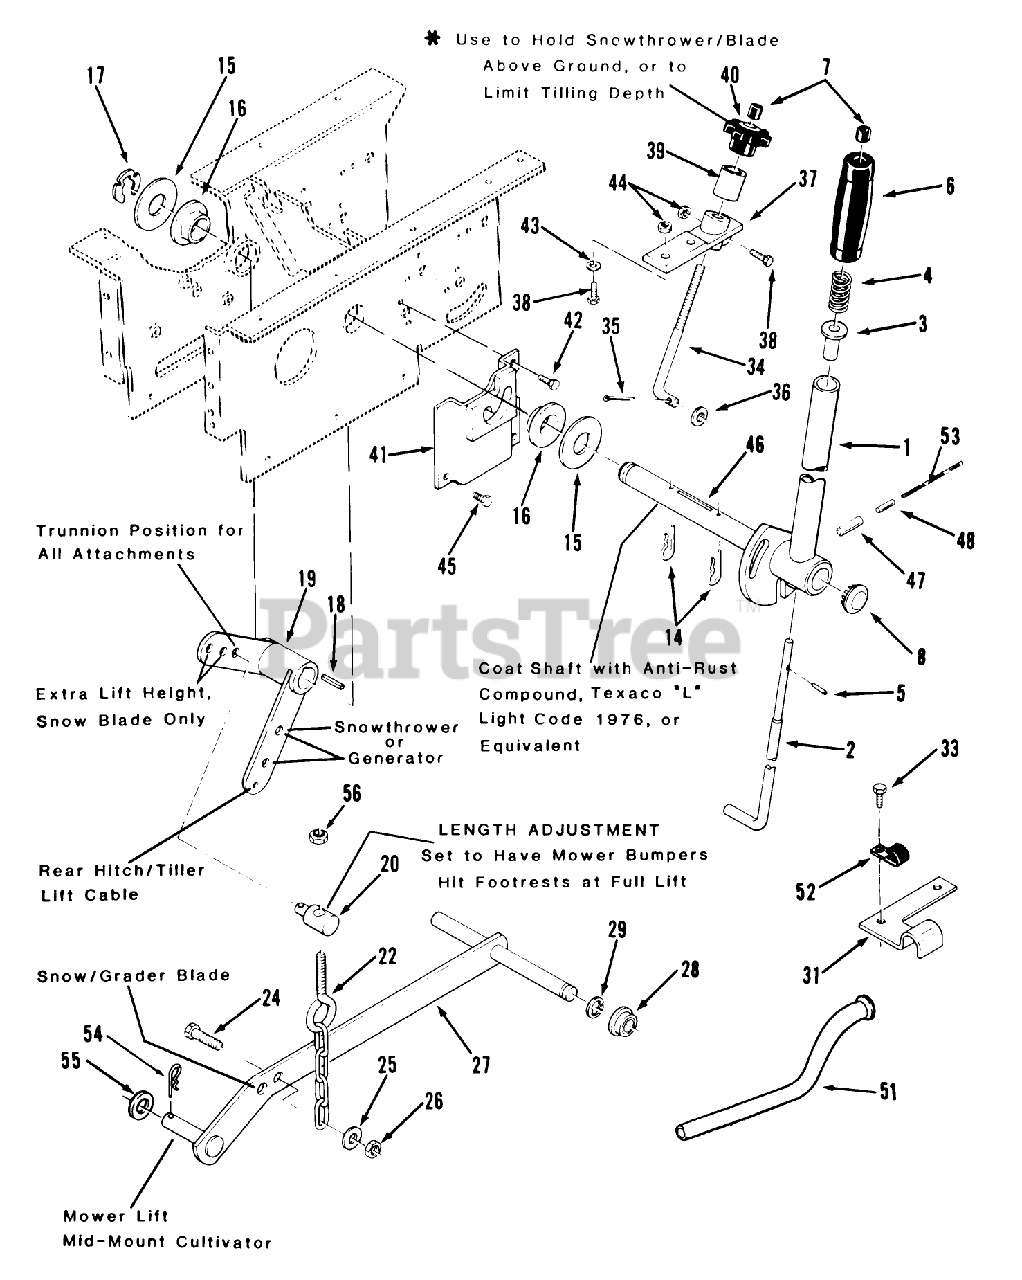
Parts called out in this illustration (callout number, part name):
2	ROD-LATCH LIFT
3	RETAINER-SPRING
4	SPRING-COMPRESSION
5	PIN-SPIROL
6	HANDGRIP
7	CAP-ROD, PLUNGER
8	PLUG
14	Pin-Cotter
16	BEARING-FLANGE
18	KEY-SQUARE
20	TRUNNION-LIFT
21	Hairpin Cotter
22	CHAIN-LIFT
25	WASHER 5/16 SAE
28	BUSHING
34	ROD-HEIGHT CONTROL
40	KNOB-LIFT CONTROL
42	SCREW
43	WASHER 5/16 SAE
46	SHAFT-LIFT LEVER
47	SPIROL PIN
48	Roll Pin
52	CLIP
53	Lock Wire
54	Hairpin Cotter
